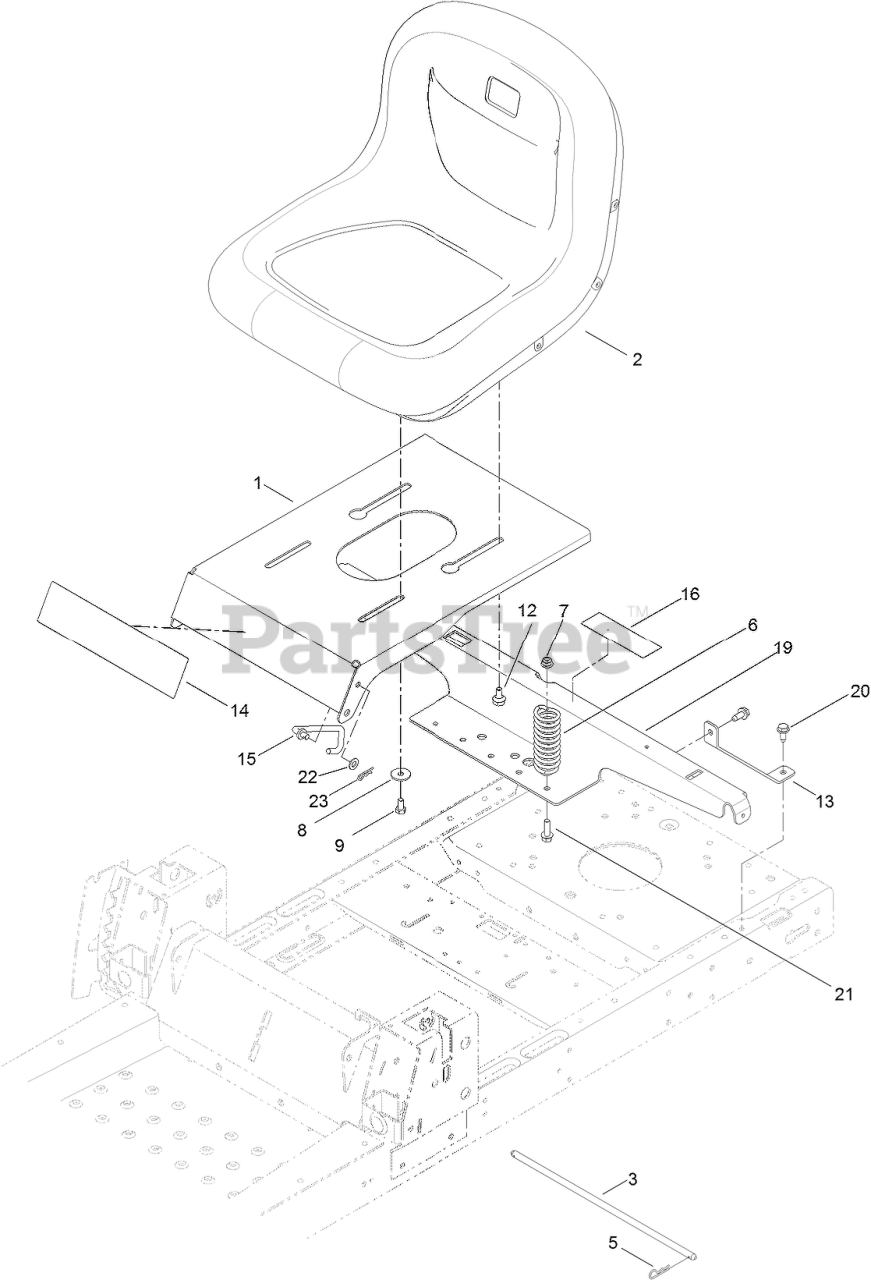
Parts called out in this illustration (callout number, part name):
1	PAN-SEAT
2	SEAT-15 INCH
3	ROD-PIVOT, NARROW
5	PIN-COTTER
6	SPRING-COMPRESSION
7	NUT-HF, NI
8	WASHER-PIVOT
9	SCREW-HH
12	BOLT-SHOULDER
13	SUPPORT-TANK, REAR
14	DECAL-TIMECUTTER
15	STOP-SEAT
16	DECAL-SERVICE, CE
19	SUPPORT-POD
20	SCREW-HWHTF
21	SCREW-HHF
22	WASHER-PLAIN
23	PIN-COTTER
